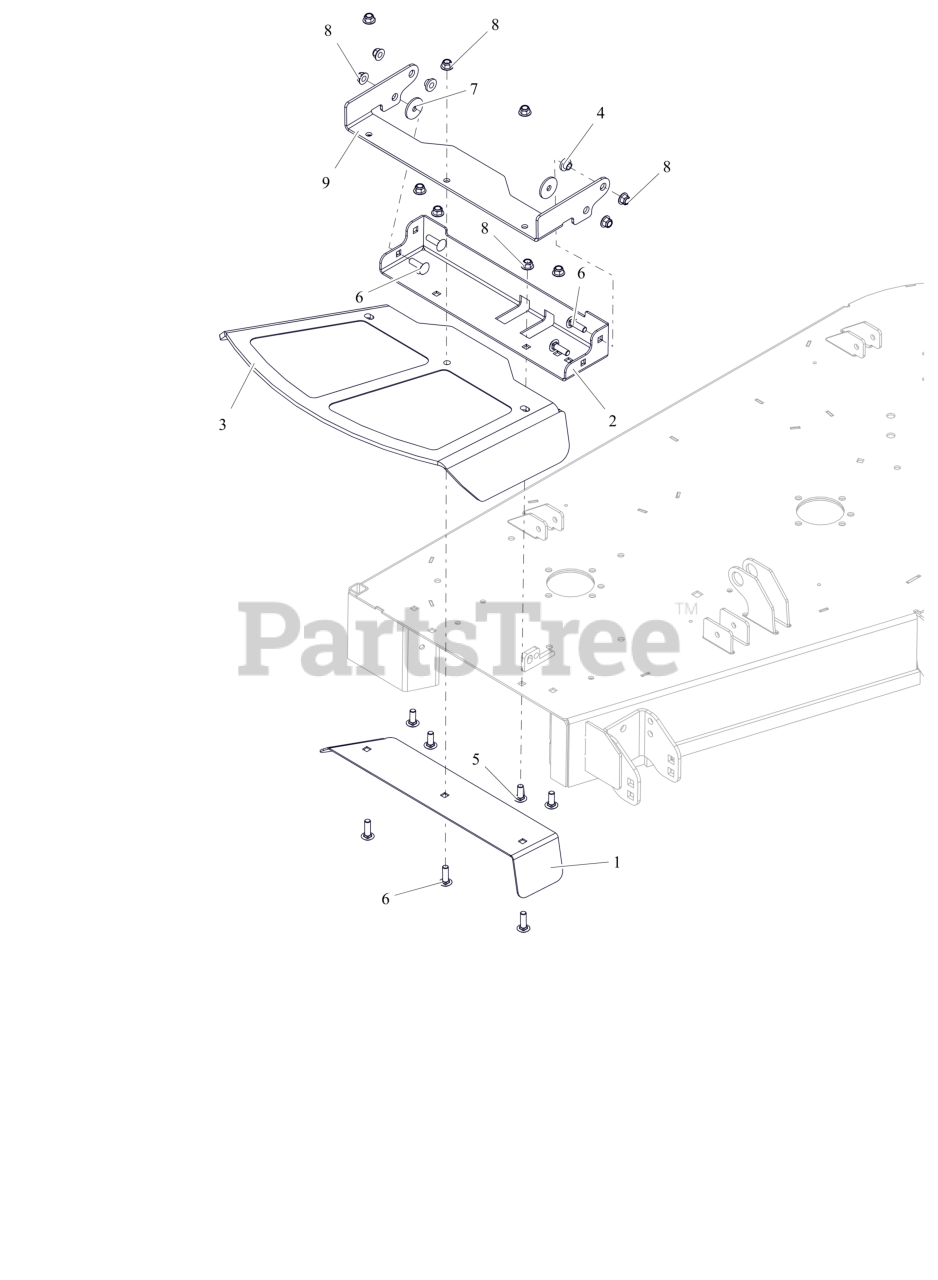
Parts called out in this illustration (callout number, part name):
1	PLT, DISCH. CHUTE CLMP-CE
2	WMT, DISCH. CHUTE-CE-W/SAFETY
3	CHUTE, FORMED RUBBER DISCHARGE
4	BSHG-FLG .385X.500X.875X.406
5	BLT,RHSSN .38-16X1.00 G5 ZCC
6	BLT,RHSSN .38-16X1.25 G5 ZCC
7	WSHR, FLT .380X1.50X.125 ZCC
8	NUT,NYL-FLG .38-16 GF ZCC
9	BRKT, CE CHUTE MTG (ORANGE)
